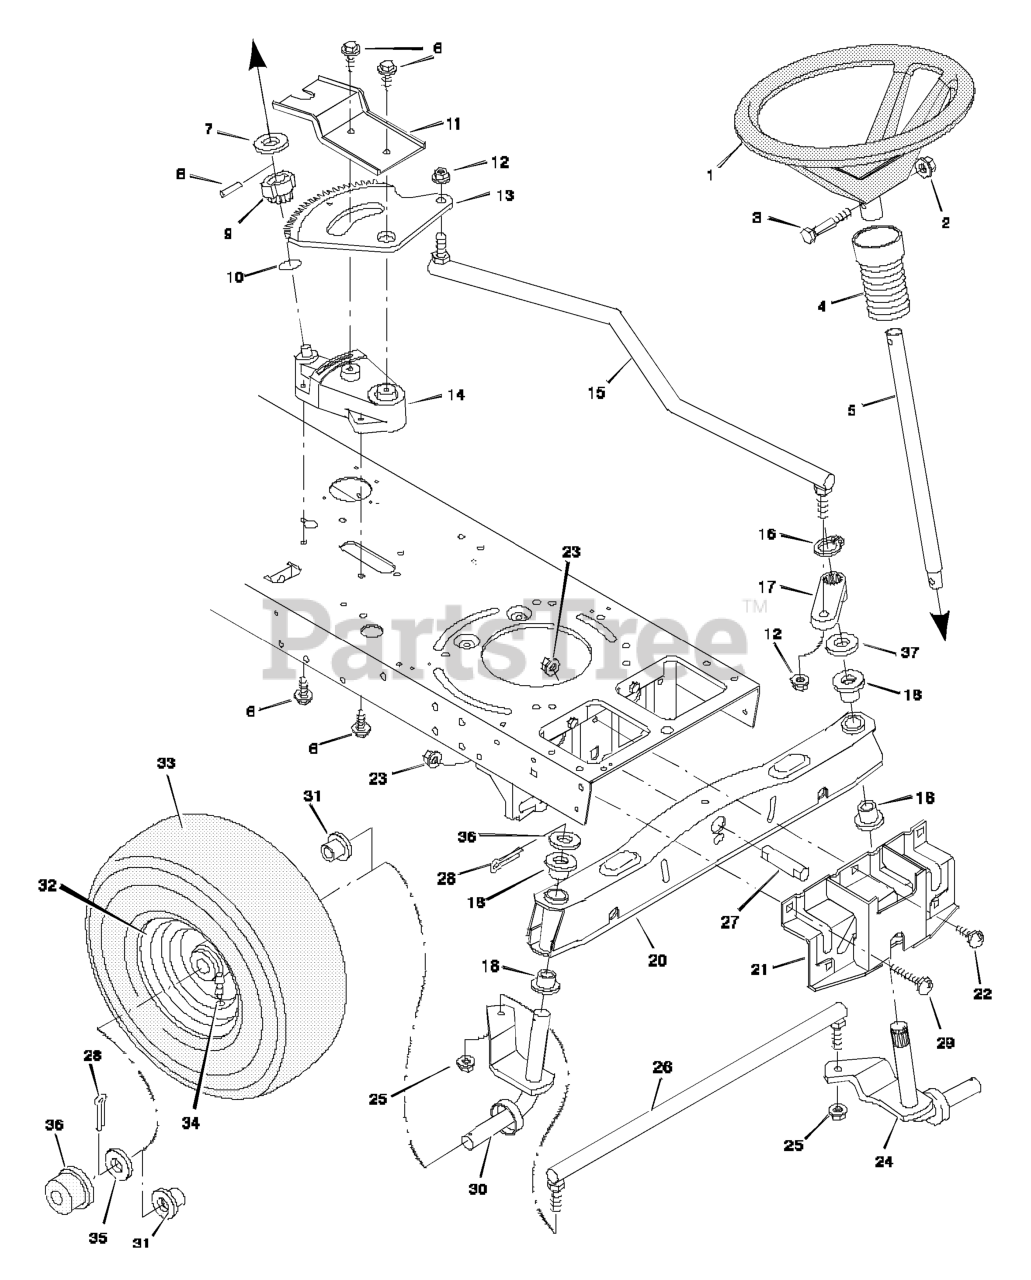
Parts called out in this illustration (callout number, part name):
1	Wheel, Steering
2	Nut, Hex
3	Bolt, Hex
4	Bellows
5	Post Assembly, Steering
7	Washer
8	Pin, Spring
9	Gear Assembly, Pinion
10	O-Ring
11	Clip, Gear Retainer
12	Locknut, Flange
13	Gear, Sector
14	Support, Steering
15	Link, Drag
16	E- Ring
17	Arm, Drag Link
18	Bearing
20	Axle Assembly (with grease fittings)
21	Hanger Assembly, Axle
22	Bolt, Carriage
23	Locknut, Flange
24	Spindle Assembly, Left
25	Locknut, Flange
26	Rod, Tie
27	Pin, Pivot
28	Pin, Cotter
29	Bolt, Carriage
30	Spindle Assembly, Right
31	Bearing, Wheel
32	Wheel & Tire Assembly
33	Tire *
34	Stem, Valve
36	Hub Cap
